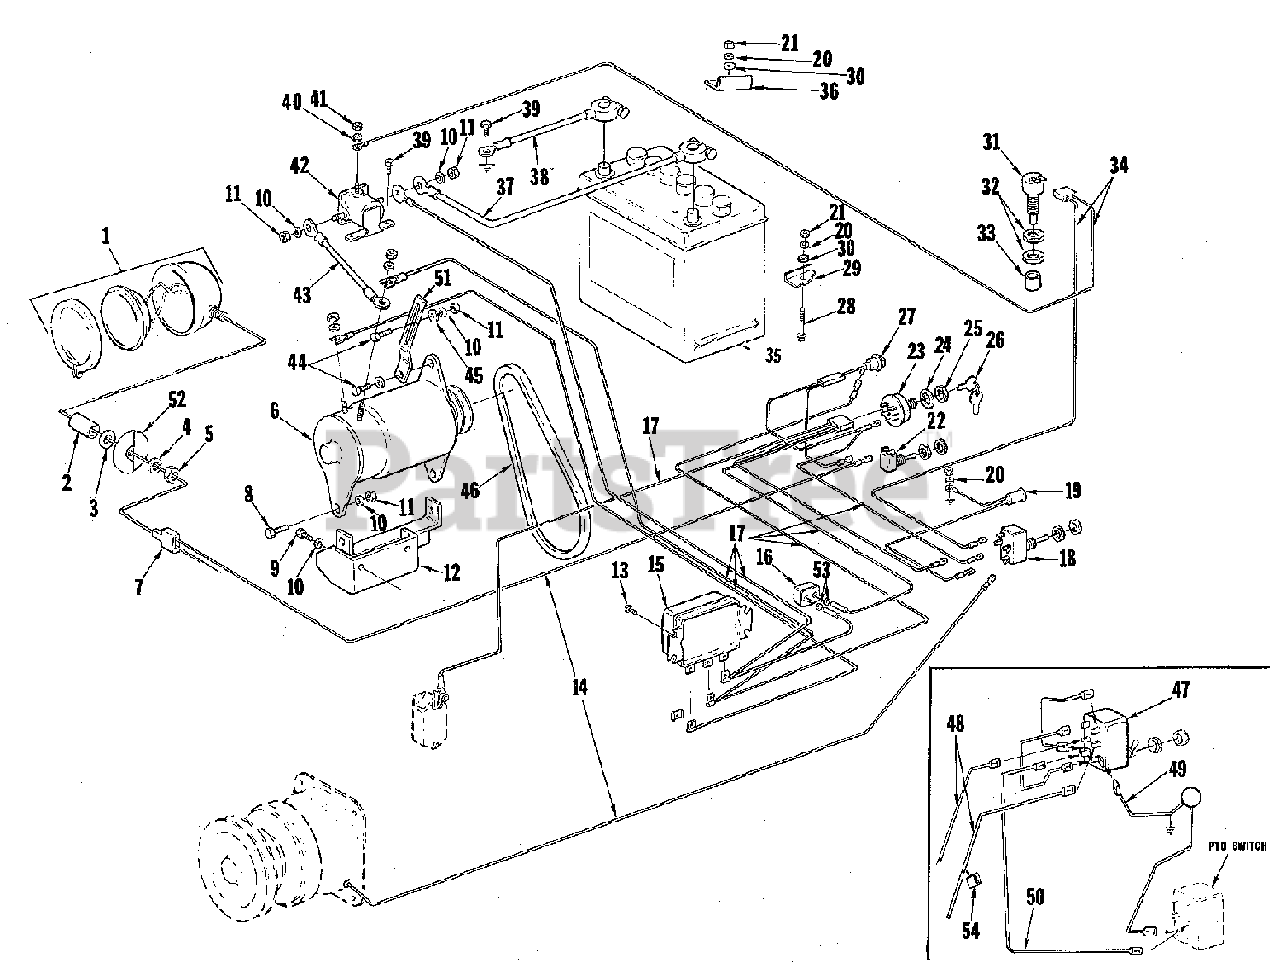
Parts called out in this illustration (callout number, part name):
1	LAMP ASSEMBLY
2	SPACER, Headlight
3	WASHER, Flat, 17/32
4	WASHER, Lock, 1/2
5	NUT, Hex Fin, 1/2-13
6	MOTOR, Generator
7	CONNECTOR, Insulated
8	SCREW, Hex Head Cap, 5/16-18 x 1-1/4
9	SCREW, Hex Head Cap, 5/16-18 x 3/4
10	WASHER, Lock, Regular, 5/16
11	NUT, Hex Fin, 5/16-18
12	SUPPORT ASSEMBLY, Generator
13	SCREW, Tapping (Taptite) 1/4-20 x 5/8
14	HARNESS ASSEMBLY, Light & PTO
15	REGULATOR, Voltage
16	BREAKER, Circuit
17	HARNESS ASSEMBLY, Wiring
18	SWITCH TOGGLE, PTO
19	LIGHT, Pilot
20	WASHER, Lock, 1/4
21	NUT, Hex, 1/4-20
22	SWITCH, Light Toggle
27	INDICATOR, Lamp Assembly
28	SCREW, Hex Head Cap, 1/4-20 x 2
29	CLAMP, Battery
31	SWITCH, Safety
32	NUT, Hex Special
33	BOOT, Rubber
34	WIRE ASSEMBLY, Switch
36	CLAMP, Battery
37	CABLE, Battery To Solenoid
38	CABLE, Battery to Ground
39	SCREW, Taptite, 1/4-20 x 1/2
40	WASHER, Lock, Extension Tooth #10
41	NUT, Machine Screw Hex, 10-32
43	CABLE, Generator to Solenoid
44	SCREW, Hex Head Cap, 5/16-18 x 3/4
45	WASHER, 5/16
46	BELT, Generator
47	SWITCH, Toggle, Actuator (T-15)
48	HARNESS, Switch to Actuator (T-15)
49	LEAD, Switch to Ground (T-15)
50	LEAD, Switch to PTO Switch (T-15)
51	ARM, Belt Tightener
52	KIT, Headlight Reinforcement
53	WASHER, Insulation
54	CLIP, Speed (T-15)
